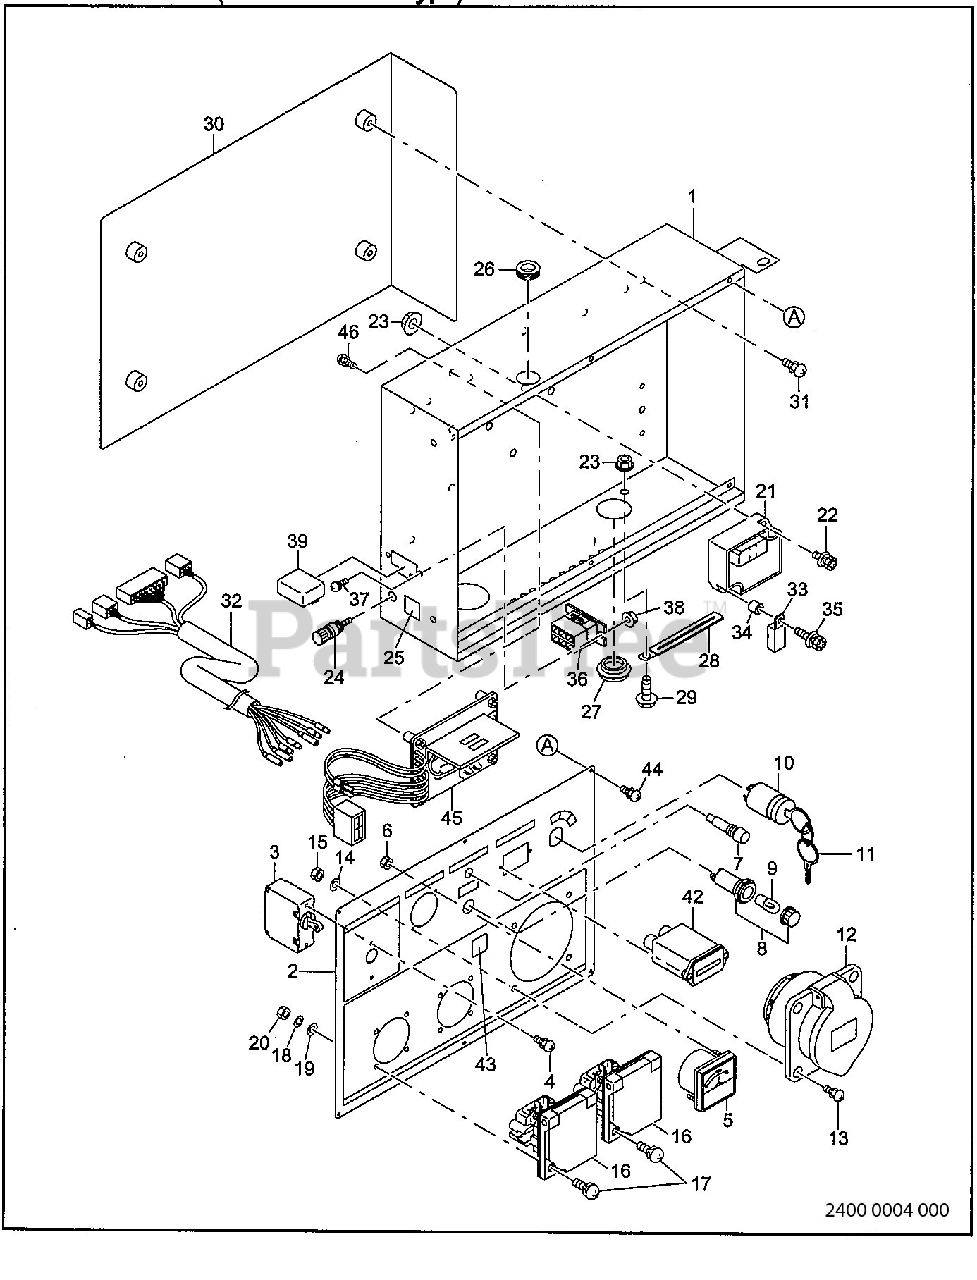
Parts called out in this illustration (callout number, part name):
1	CONTROL BOX ASSY
1	CONTROL BOX UNIT
2	CONTROL PANEL ASSY
2	CONTROL PANEL
3	BREAKER (1P-36A)
4	SCREW and WASHER ASSY
8	LAMP (OIL)
9	LAMP (18V-0.11A)
10	KEY SWITCH
12	AC RECEPTACLE (240V-32A)
13	SCREW and WASHER ASSY
16	AC RECEPTACLE (250V-16A)
17	SCREW
21	ECU(O/S & R/C) ASSY
22	SCREW and WASHER ASSY
23	FLANGE NUT
29	FLANGE BOLT
31	SCREW and WASHER ASSY
32	WIRE ASSY
35	SCREW
36	CONNECTOR (6P)
37	SCREW and WASHER ASSY
43	LABEL(elec shock)
44	SCREW and WASHER ASSY
45	AVRASSY
46	SCREW and WASHER ASSY
